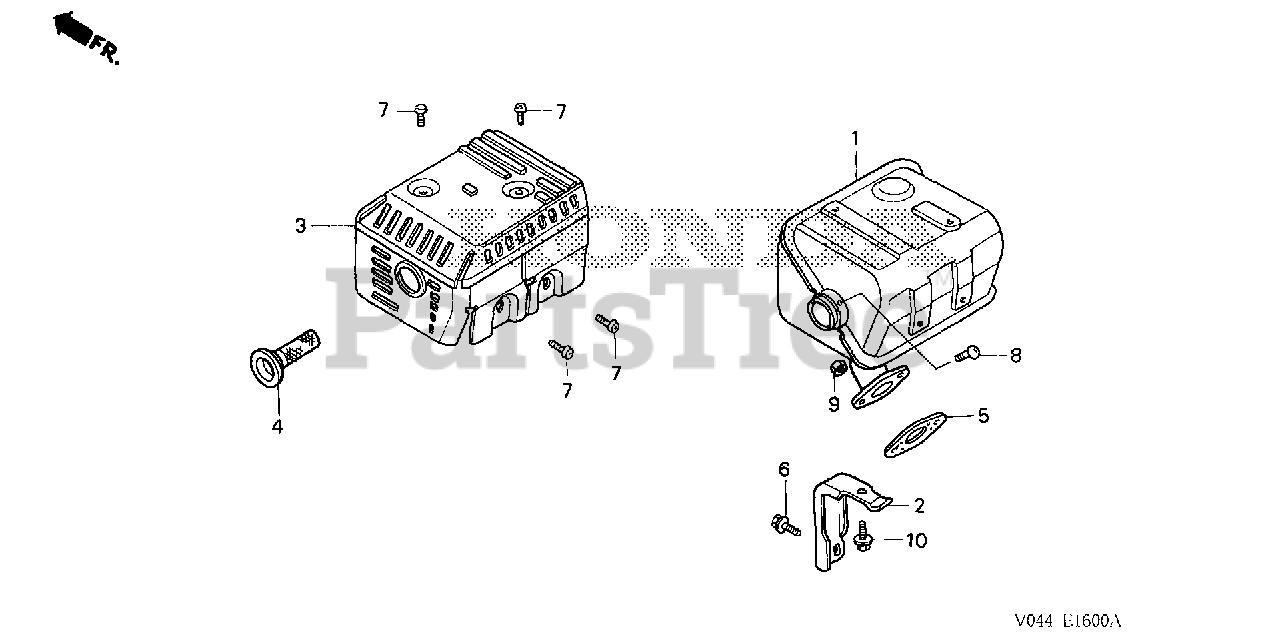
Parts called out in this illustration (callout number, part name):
1	MUFFLER (SILENT)
2	STAY, MUFFLER
3	PROTECTOR, MUFFLER
3	PROTECTOR, MUFFLER (SILENT)
4	ARRESTER, SPARK (SILENT)
5	GASKET, MUFFLER
6	BOLT, FLANGE (6X13)
7	SCREW, TAPPING (5X8)
8	SCREW, TAPPING (4X6)
9	NUT, HEX. (8MM)
10	BOLT, FLANGE (6X12) Use up to Engine SN 1543277.
